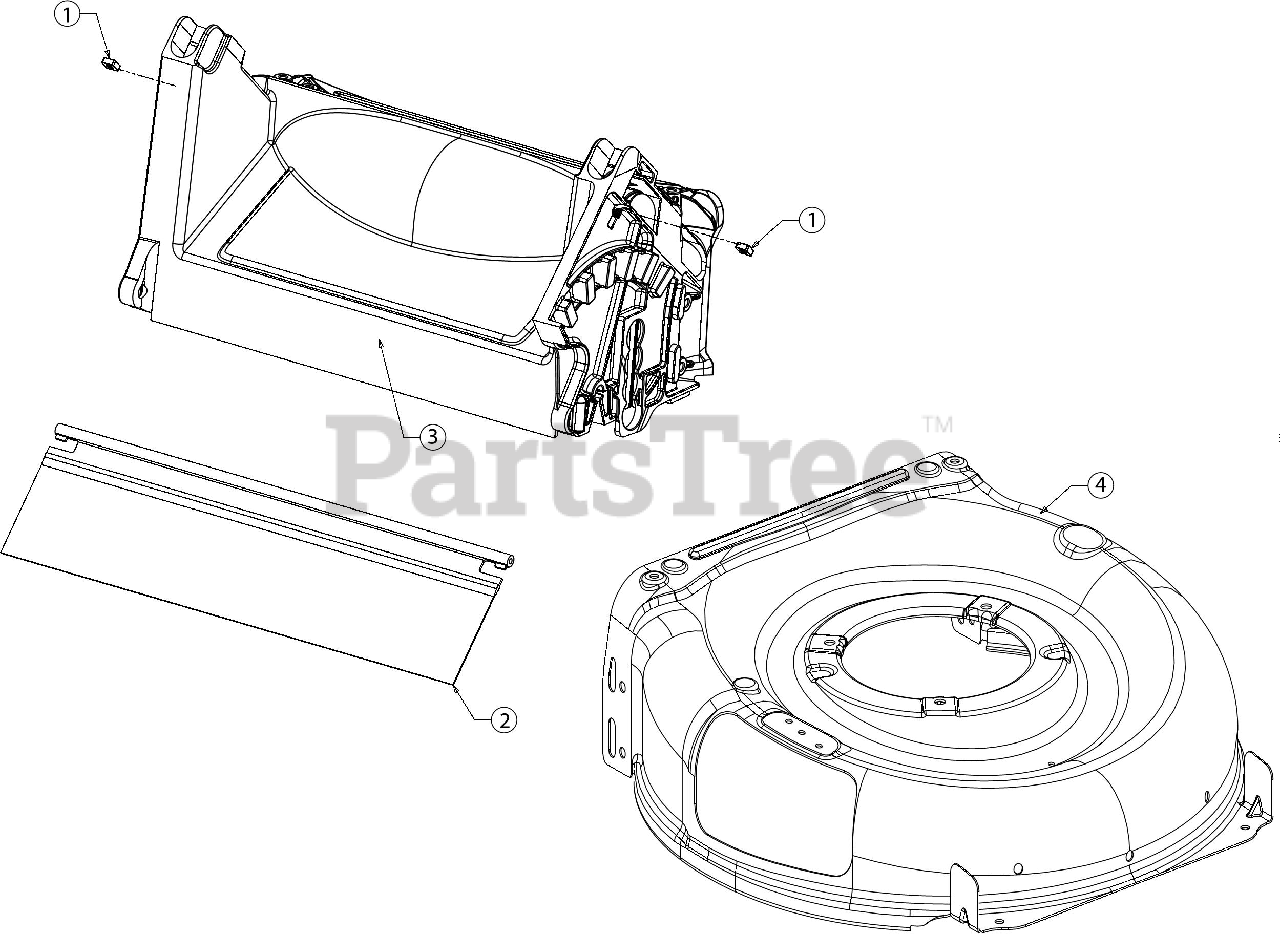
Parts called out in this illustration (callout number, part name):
1	SQUARE NUT 1/4-20
2	TRAILSHIELD
3	REAR BAFFLE ASSEMBLY
4	21" DECK (3N1)
